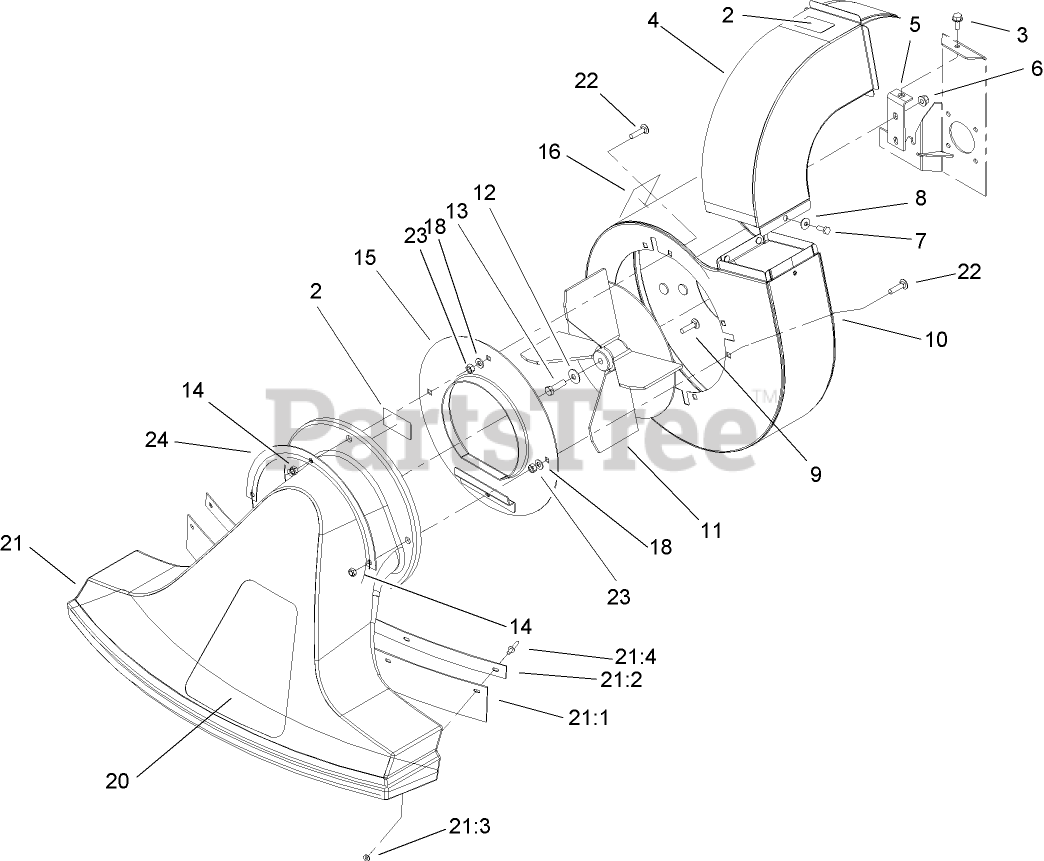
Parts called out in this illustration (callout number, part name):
2	DECAL-CAUTION, BAG
3	SCREW-HWHTF
4	VACUUM CHUTE ASM
5	BRACKET-MOUNTING, HOUSING
6	NUT-LOCK, NI
7	SCREW-HH
8	WASHER-BELLEVILLE
9	BOLT-CARR
10	HOUSING-BLOWER
11	FAN ASM
12	WASHER-BELLEVILLE
13	SCREW-HH
14	NUT-LOCK, NI
15	COVER-BLOWER
16	DECAL-WARNING, ROTATE
18	WASHER-PLAIN
21	SNOUT ASM
21:1	FLAP-RUBBER
21:2	CLAMP-FLAP
21:3	WASHER-FLAT
21:4	RIVET-POP
22	SCREW-CARR
23	NUT-HEX
24	FLANGE-RETAINER
